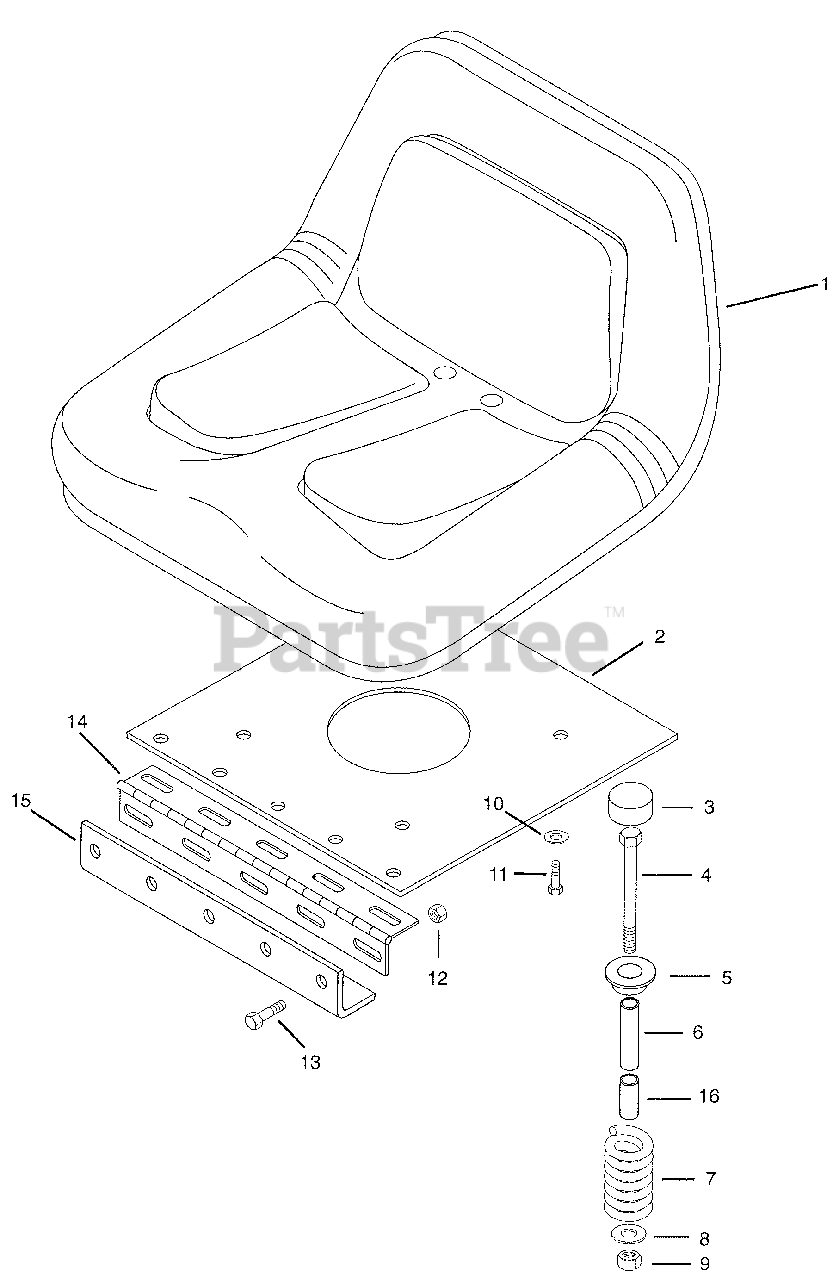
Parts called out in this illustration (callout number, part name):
1	Seat, V-560 High Back
2	Plate, Seat Mounting
3	Tip, Rubber
4	Bolt Hex .25-20 X 2.25
5	Cap, Valve Spring
6	Bushing, Split Rolled
7	Spring, Compression .148 X 1.095 X 1.75
8	Washer Flat Steel .344 X .688 X .065
9	Nut Locking Nylon .250-20 Grade 2
10	Washer Lock .313 X .078
11	Bolt Hex Metric 8M-1.25 X 35MM Grade 8
12	Nut Locking Nylon .312-18 Grade 2
13	Bolt Hex .31-18 X .625
15	Bracket, Seat Support
16	Bushing, Split Rolled (010, 011)
